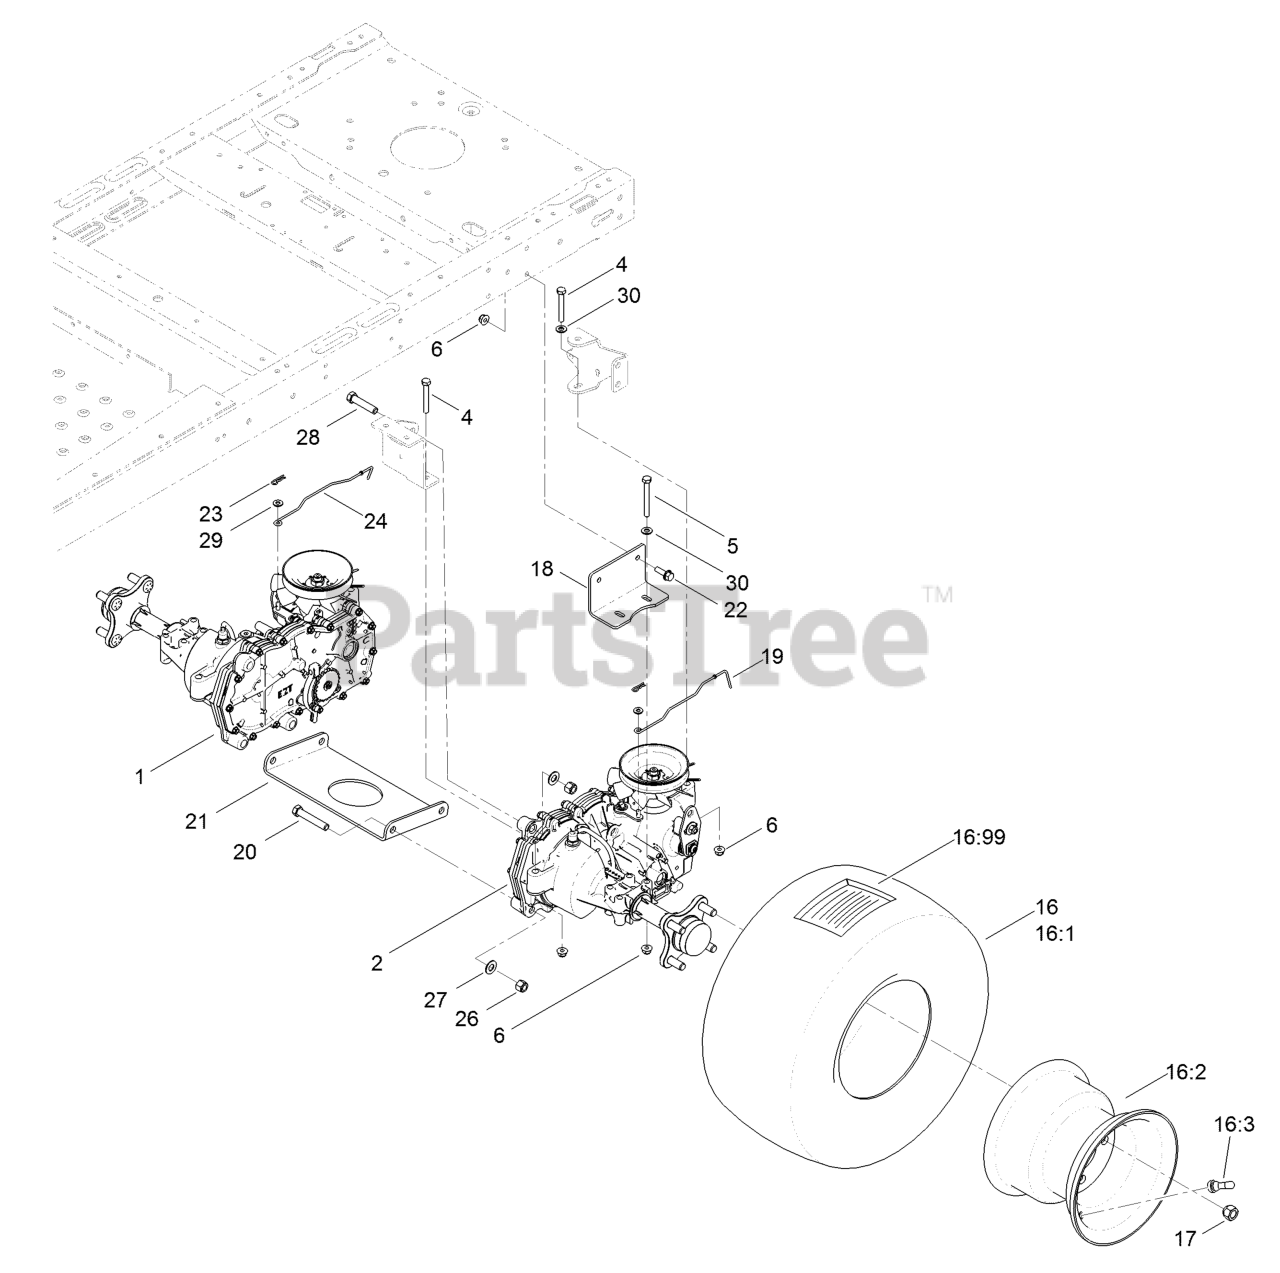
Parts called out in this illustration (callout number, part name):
1	RH HYDRO TRANSAXLE ASM
2	LH HYDRO TRANSAXLE ASM
4	SCREW-HH
5	SCREW-HH
6	NUT-HF, NI
16	4 PLY WHEEL AND TIRE ASM
16:1	TIRE-4 PLY
16:3	Stem-Valve
16:99	TUBE-TIRE
17	NUT-LUG
18	MOUNT-HYDRO
19	ROD-BYPASS, LH
20	SCREW-HH
21	PLATE-CROSS, HYDRO
22	SCREW-HHF
24	ROD-BYPASS, RH
26	NUT-LOCK, NI
27	WASHER-FLAT
28	SCREW-HH
30	WASHER-PLAIN
